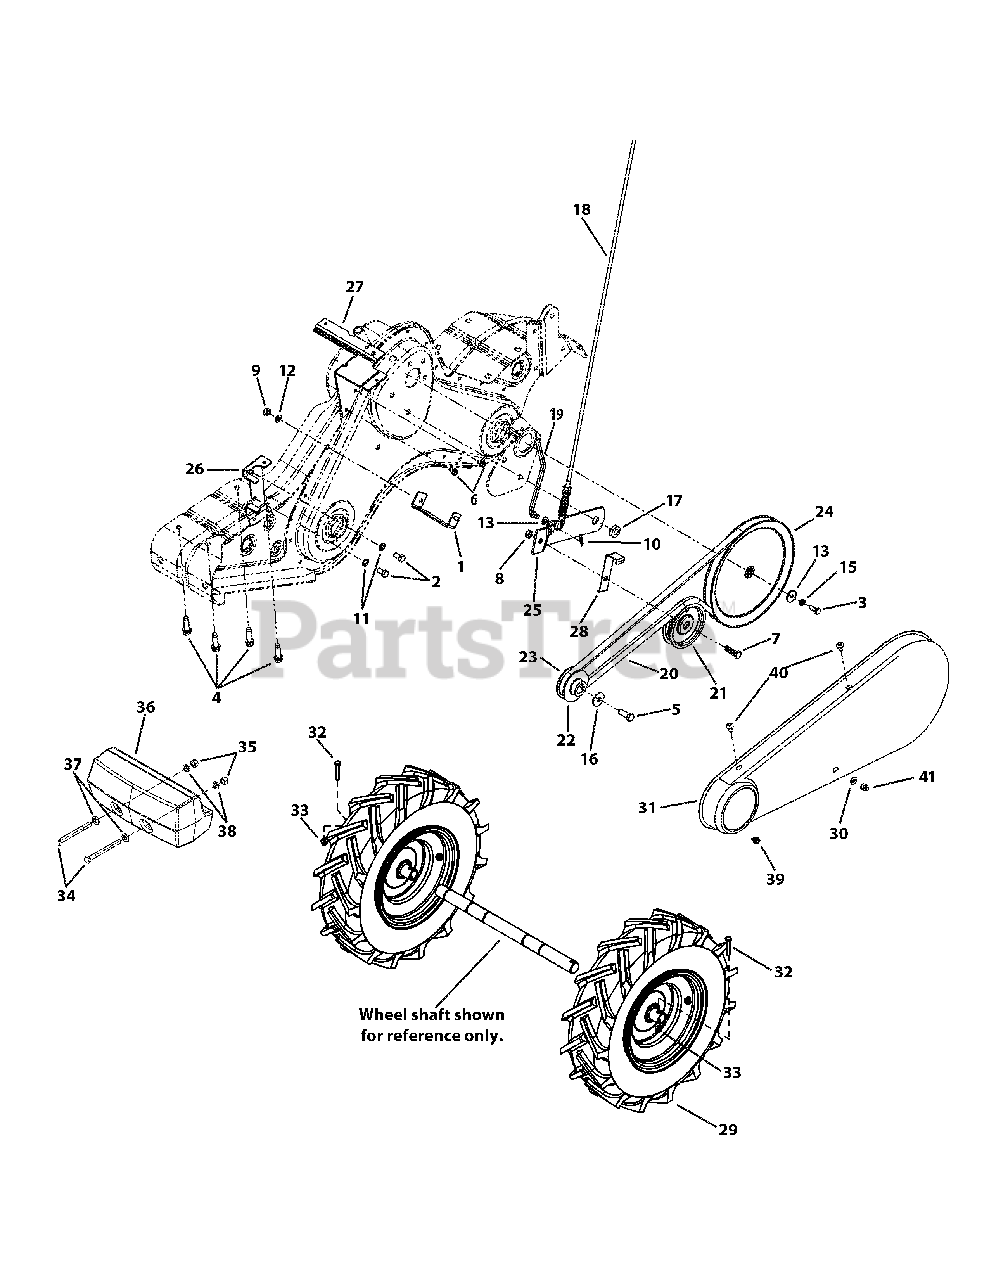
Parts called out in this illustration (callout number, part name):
1	Belt Cover Bracket Assembly
2	Hex Bolt, 5/16-24 x .62"
3	Hex Bolt, 1/4-28 x .75"
4	Hex Washer Screw, 3/8-16 x 1.50"
5	Hex Bolt, 3/8-24 x 1.0
6	Hex Washer Screw
7	Hex Cap Screw, 3/8-16 x 1.25
8	Lock Jam Nut, 3/8-16
9	Hex Nut, 5/16-18
10	Internal Cotter Pin
11	Hairpin Clip
12	Lock Washer, 5/16"
13	Flat Washer, .25 ID x .93 OD
14	Spring Washer, .317 ID x .625 OD
15	Lock Washer, 1/4" ID
16	Bell Washer, .396 ID x 1.14 OD
17	Shoulder Nut, 7/16-20
18	Clutch Cable
19	Idler Pulley Rod
21	Flat Idler w/ Flange, 3.75 OD
22	Outer Engine Pulley Half
23	Inner Engine Pulley Half
24	Input Pulley
25	Idler Bracket
26	Belt Keeper Bracket
27	Shift Cover Bracket
28	Idler Belt Keeper
29	Wheel Assembly, 16.0 x 4.6 x 8
30	Flat Washer, .271 ID x .630 OD
31	Belt Cover
32	Hex Head Screw, 1/4-20
33	Flange Lock Nut, 1/4-20
34	Hex Bolt, 1/2-13 x 5.0
35	Hex Nut, 1/2-13
36	Counterweight, 40 lbs.
37	Flat Washer
38	Lock Washer, 1/2
39	Hex Screw, 1/4-20 x .375
40	Screw, 1/4-14 x .625
